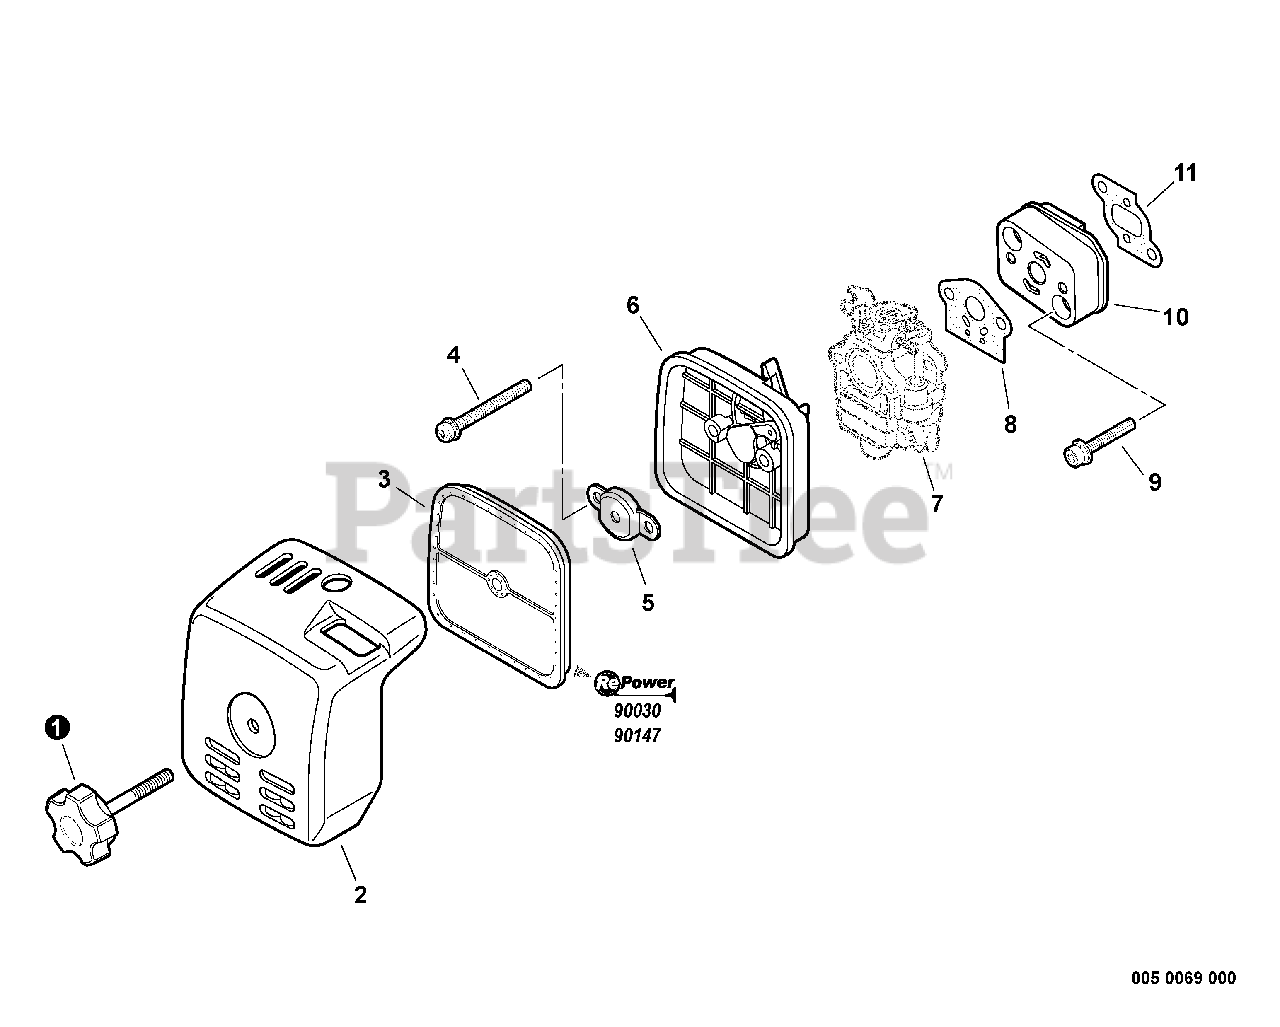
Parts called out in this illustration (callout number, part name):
1	THUMBSCREW
2	COVER, AIR FILTER
3	FILTER, HEAVY-DUTY AIR
4	SCREW 5×60
5	PLATE, PREVENT
6	CASE, AIR FILTER
7	CARBURETOR
8	GASKET, CARBURETOR
9	BOLT 5×25
10	INSULATOR, INTAKE
11	GASKET, INTAKE
12	REPOWER FILTRATION KIT
13	TUNE-UP KIT
